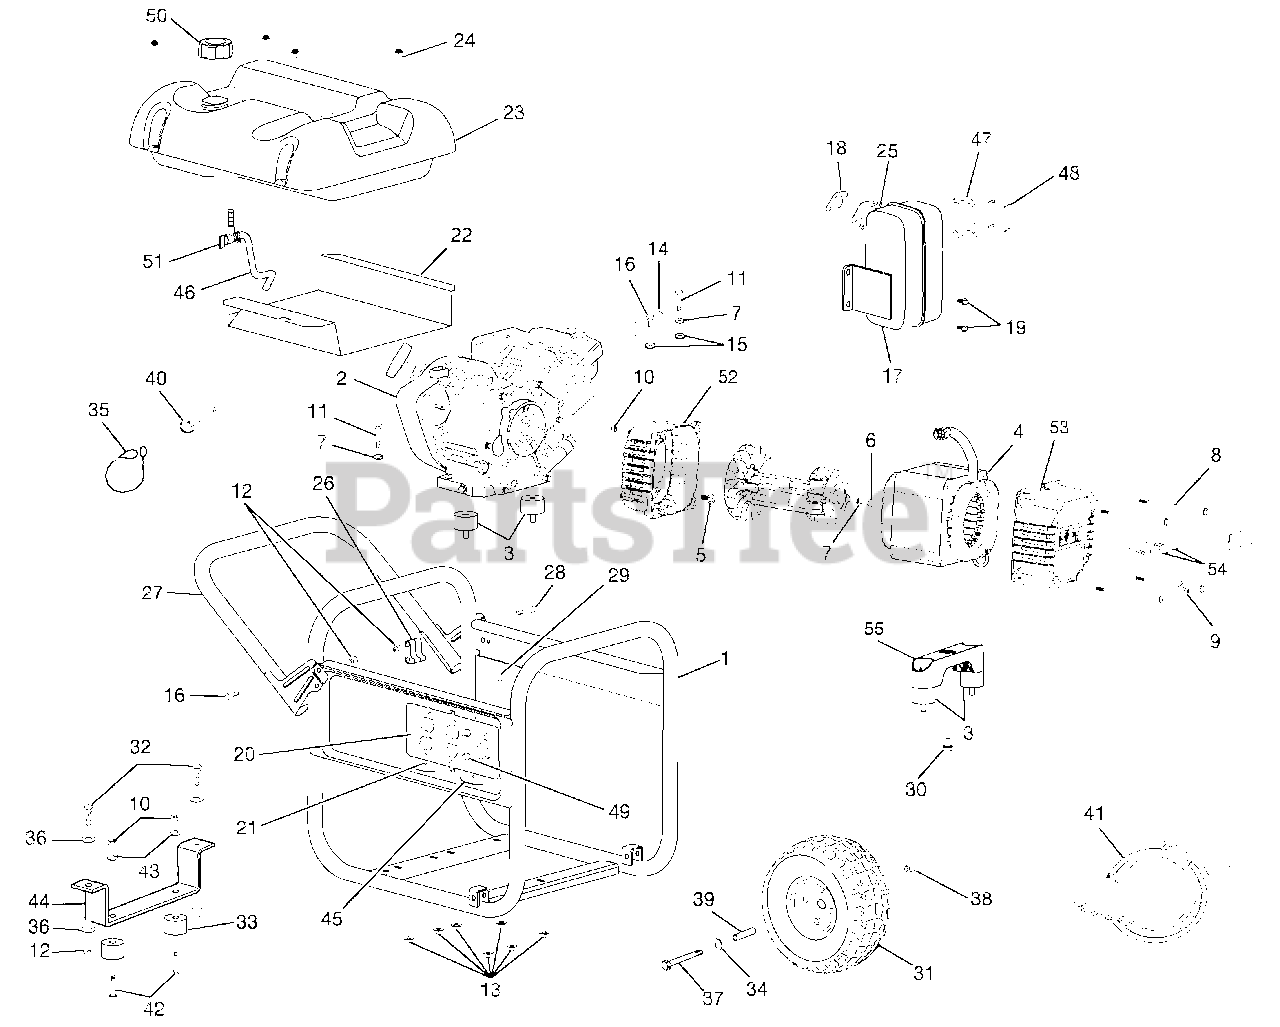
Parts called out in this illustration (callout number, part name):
1	Frame Assembly
2	Engine (Subaru OHC)
4	Generator Head Assembly
5	Bolt (3/8-16 x 3/4 in.)
6	Bolt (5/16-24 x 6-5/8 in., Hex Hd.)
7	Lock Washer (5/16 in.)
8	Bolt (1/4-20 x 6 in., Hex Hd.)
9	Ground Lug
10	Lock Nut (1/4-20)
11	Bolt (5/16-18 x 1-1/2 in.)
12	Lock Nut (5/16-18)
13	Flange Nut (5/16-18)
14	Ground Wire Assembly
15	Washer (5/16 in.) External Star
16	Bolt (5/16-18 x 3/4 in., Hex. Hd.)
19	Bolt (5/16-24 x 5/8 in.)
20	Wire Panel
21	Screw (6-19 x 1/2 in.)
22	Heat Shield
23	Fuel Tank Assembly
24	Screw (#10 x 1 in.)
25	Nut (8 mm)
26	Handle Lock Bracket
28	Bolt (5/16-18 x 1-3/4 in.)
29	Rubber Cap
30	Bolt (5/16-24 x 5/8 in.)
31	Wheel (10 in.)
32	Bolt (5/16-18 x 1 in.)
33	Rubber Foot
34	Washer (3/8 in.)
36	Washer (5/16 in.)
37	Bolt (3/8-16 x 4-1/4 in.)
38	Lock Nut (3/8-16)
39	Spacer (.38 ID)
40	Handle Lock Pin
41	Extension Cord (25 foot, 20 amp)
42	Bolt (1/4-20 x 1-1/2 in.)
43	Washer (1/4 in.)
44	Frame Support
45	Cord Retainer
46	Fuel Line Assembly
47	Spark Arrester Screen
48	Screw (8-32 x 3/8 in.)
49	Circuit Breaker (25 amp)
51	Fuel Shut Off with Filter
52	Adapter Housing
54	Brush Assembly
